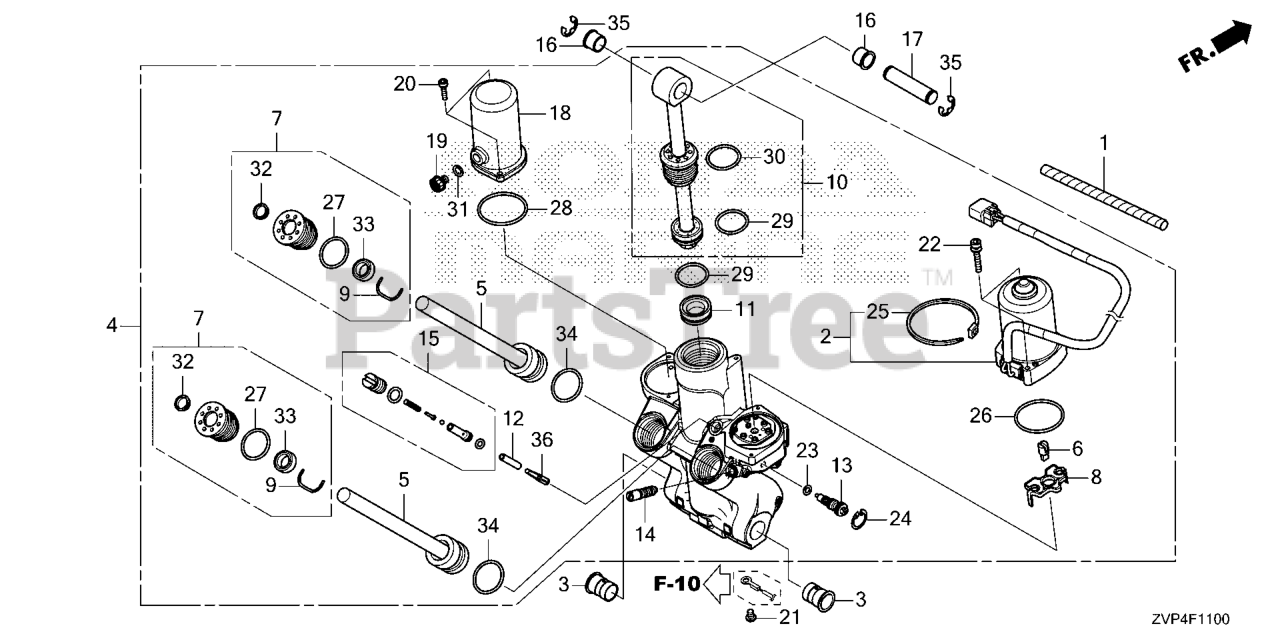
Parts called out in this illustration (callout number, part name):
1	TUBE, SPIRAL (12X14.6)
2	MOTOR, POWER TILT
3	BUSH, SWIVEL CASE
5	PISTON ROD
6	JOINT, DRIVE
7	GUIDE COMP, ROD
9	GROUND RING
10	ROD COMP, PISTON
11	FREE PISTON COMP
13	MANUAL VALVE COMP
14	VALVE COMP
16	BUSH, CYLINDER (LOWER)
17	PIN, CYLINDER (UPPER)
19	CAP, OIL TANK
20	BOLT, SOCKET (5X0.8)
21	SCREW, PAN (6X8)
22	BOLT (M6X1.0)
23	WASHER, SEAL
24	CIRCLIP (INNER)
25	BAND, WIRE HARNESS
26	O-RING (1.8X69.6)
27	O-RING (3.5X38.7)
28	O-RING (1.8X69.1)
29	O-RING (3.5X43.7)
30	O-RING (3.5X47.7)
31	O-RING (1.8X10.8)
32	SEAL, WATER
34	O-RING (3.5X31.7)
35	E-RING (15MM)
36	FILTER (HITACHI)
